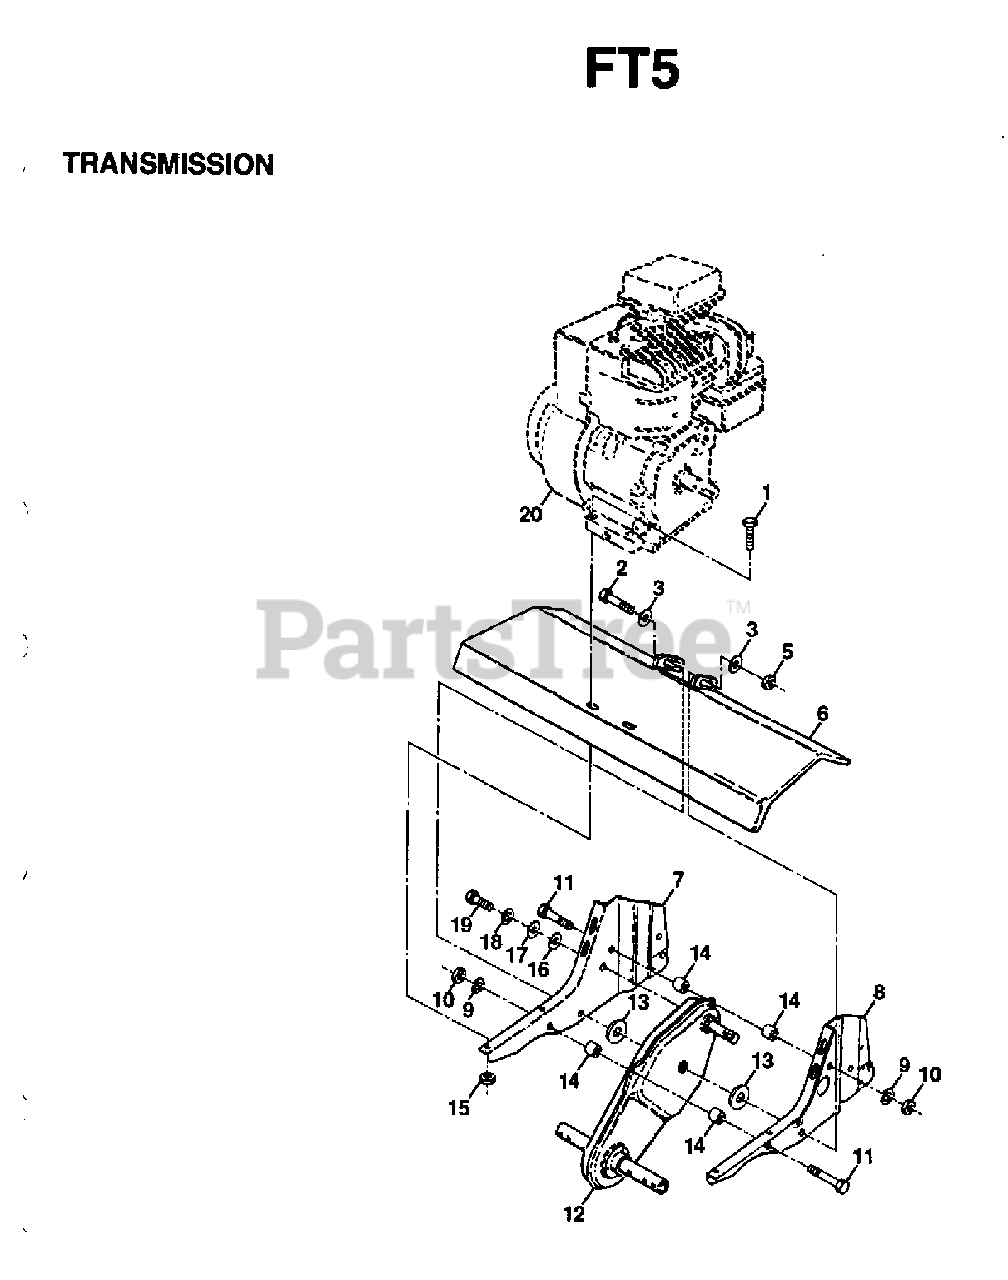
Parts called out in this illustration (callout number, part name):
1	TRANSMISSION ASSY
2	GEARCASE LH W/BRG
3	GASKET TI
4	NEEDLE BRNG LT
5	THRUST WASHER
6	GEAR.PINION.INPUT
7	SHAFT.INPUT."D".TILLER
8	BEARING TI
9	WASHER, SEAL
10	STEEL BALL KIT
11	SPRING-SHIFT CRT
12	O-RING TI
13	SHIFTING ARM
14	SHIFT FORK TI
15	KLIP RING
16	SHAFT.SHIFTER.TILLER
19	KLIP RING
20	GEAR ASSY CRT
21	GEAR-REV IDLR CRT
22	NEEDLE BEARING TI
23	SHAFT CRT
24	LOCKWASHER
27	BEARING, SHAFT LH CRT
29	CHAIN CRT
30	GROUND SHAFT ASS'Y
31	BEARING, SHAFT RH CRT
32	SPACER TI
33	SPRCKT 8 GEAR CRT
34	SHAFT.SECONDARY.REDUCTION.CRT
35	SCRW WHIZ LOK CRT
36	SPROCKET ASS'Y W/BRG
37	BEARING
38	SPROCKET, TINE
39	GEAR TI
41	SHAFT.REDUCTION.TILLER
42	BRNG RACE T
43	SPACER TI
44	SEAL ASM, OIL
48	GEARCASE RH W/BRG
49	TINE SHAFT
50	CHAIN.TILLER
51	SCREW
53	BEARING KIT
